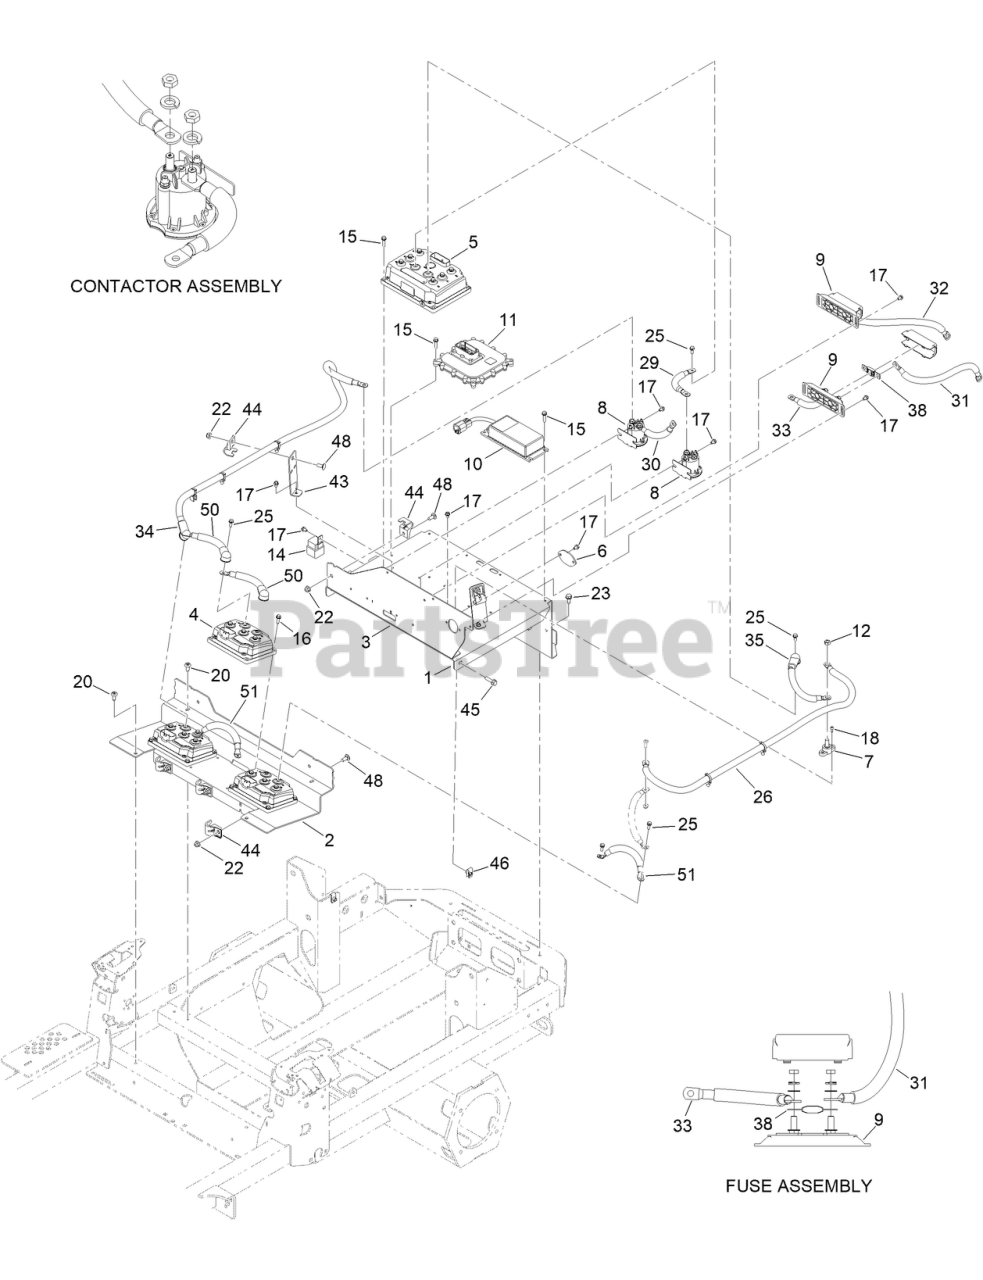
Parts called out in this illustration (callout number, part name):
1	BRACKET-CHASSIS
2	PLATE-CONTROLLER, DECK
3	PLATE-MOUNT, FUSE
4	INV/CTRLR-48V
5	INV/CTRLR-48V,DUAL 94Arms
6	PLATE-COVER
7	BLOCK-JUNCTION
8	CONTACTOR-DC, 12V
9	HOLDER-FUSE
10	CONVERTER DC-DC
11	CONTROLLER
12	NUT-HEX
14	RELAY
15	SCREW-HWHTF
16	SCREW-HWH, THREAD ROLL
17	SCREW-HWH
18	SCREW-FORMING, THREAD
22	NUT-HF, NI
23	SCREW-HWHTF
25	SCREW-SEMS
26	CABLE-BATTERY, BK ASM
29	CABLE-BATTERY, RD ASM
30	CABLE-BATTERY, RD ASM
31	CABLE-BATTERY, RD ASM
32	CABLE-BATTERY, RD ASM
33	CABLE-BATTERY, RD ASM
34	CABLE-BATTERY, RD ASM
35	CABLE-BATTERY, BK ASM
38	FUSE-200A
43	BRACKET-CABLE
44	MOUNT-CABLE
45	SCREW-HHF
46	NUT-CLIP, U
48	SCREW-CARR
50	CABLE-BATTERY, RD ASM
51	CABLE-BATTERY, BK ASM
